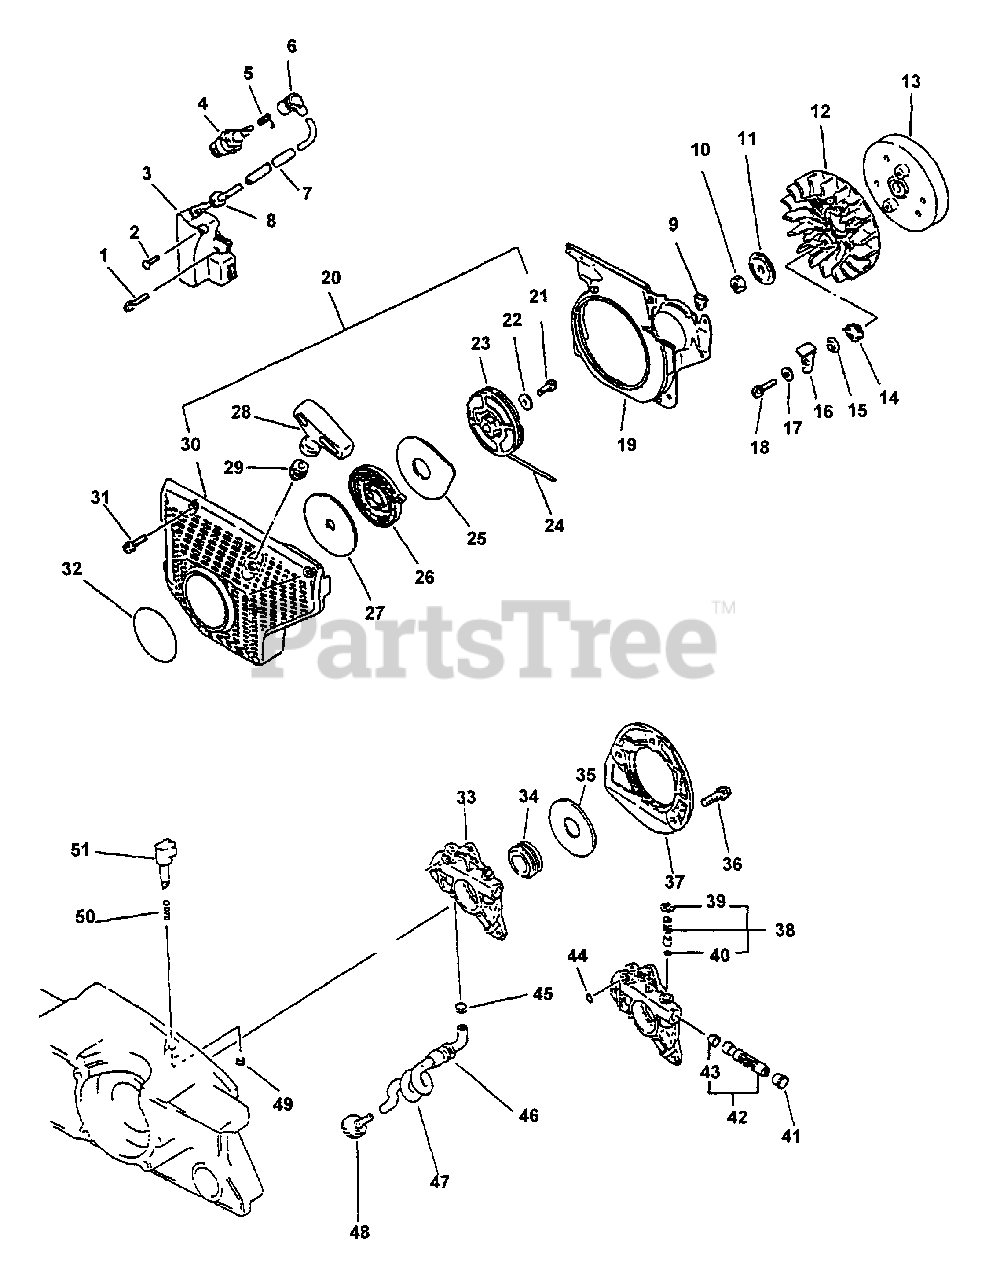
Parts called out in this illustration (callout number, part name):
1	BOLT 4×20
2	SCREW 4×8
3	COIL, IGNITION
4	SPARK PLUG - CJ-6Y
5	TERMINAL, SPARK PLUG
6	CAP, SPARK PLUG
11	WASHER 8.2×31×0.8
13	FLYWHEEL
14	SPRING, RETURN
15	SPACER, PAWL
16	PAWL, STARTER
17	WASHER 5.5×12×0.8
18	SCREW 5×14
19	COVER, FAN
20	STARTER ASSY
21	SCREW 5×14
22	WASHER 5.5×12×0.8
23	REEL, ROPE
24	ROPE, STARTER
25	PLATE, SIDE
26	SPRING, RECOIL
27	PLATE, SIDE
28	GRIP, STARTER
29	GUIDE, ROPE
30	COVER, FAN
31	SCREW 5×18
32	LABEL - ECHO
33	AUTO-OILER ASSY
34	GEAR, WORM
36	SCREW 4×12
37	COVER, OIL PUMP - GRAY
38	PIN ASSY, CONTROL
41	CAP, PLUNGER
42	PLUNGER KIT
44	O-RING 3
45	CLIP Ø6.5 MM
47	PIPE, OIL
48	FILTER, OIL
49	E-RING 3
